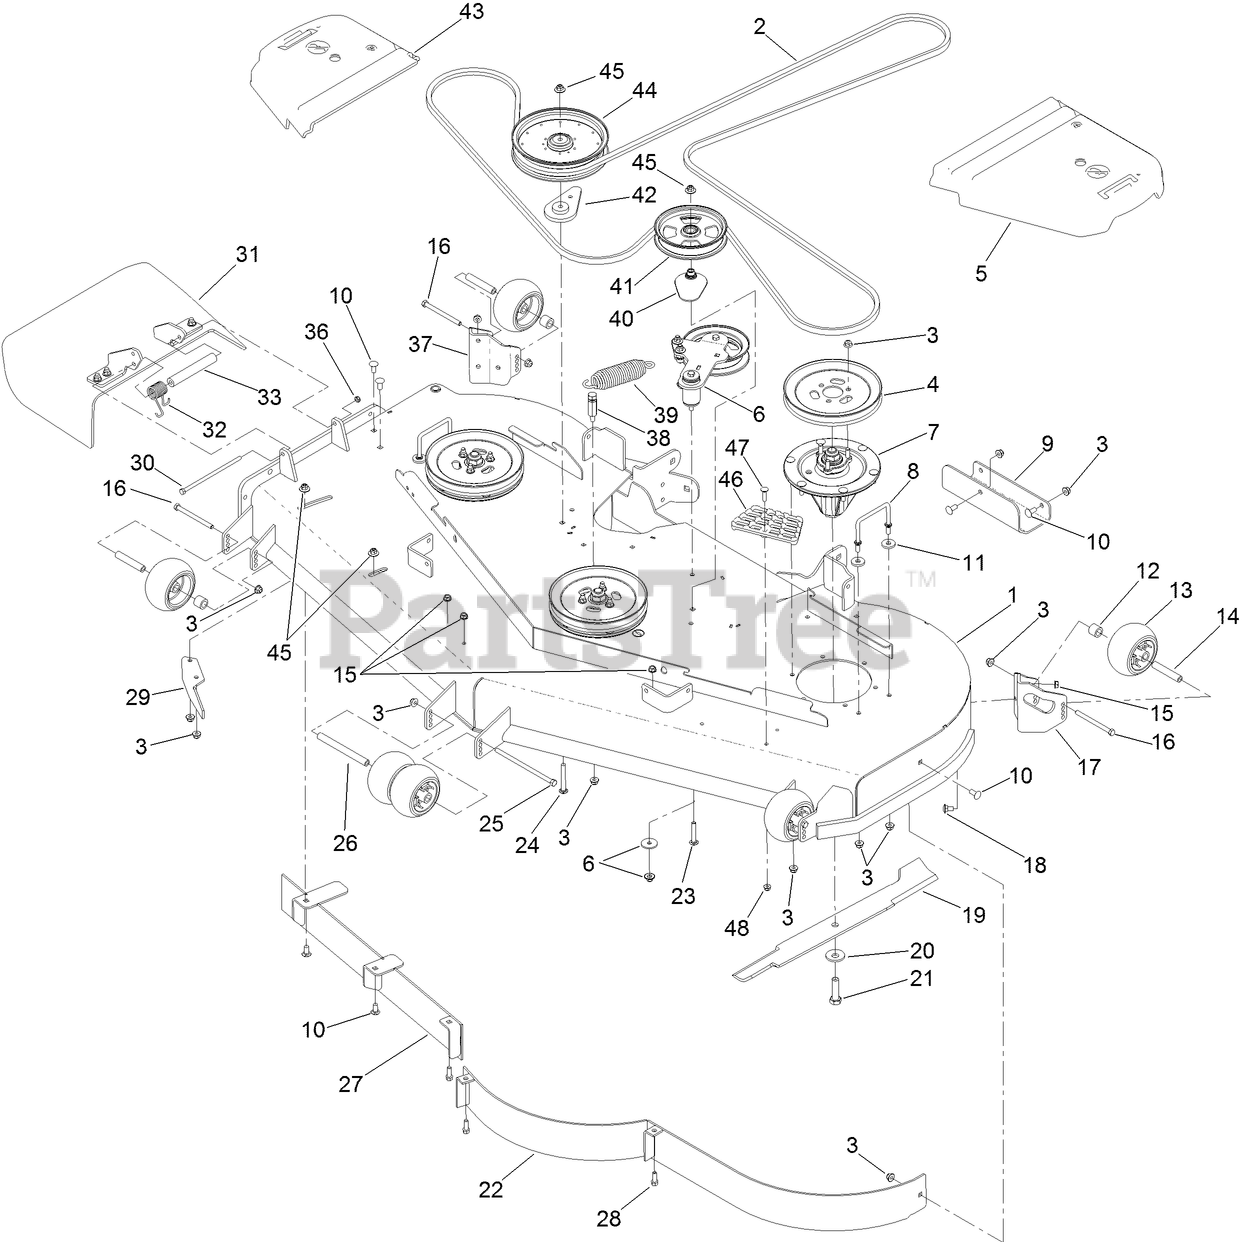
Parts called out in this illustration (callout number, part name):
1	DECK DECAL ASM
2	BELT-V
3	NUT-HF, NI
4	Pulley
5	COVER-BELT, LH
6	IDLER ARM ASM
7	SPINDLE ASM
8	WIREFORM-COVER
9	PLATE-SKID
10	SCREW-CARR
11	WASHER
12	TUBE-SPACER
13	ROLLER-SCALP, ANTI
14	TUBE-SPANNER
15	NUT-HHF, WHIZ
16	SCREW-HH
17	MOUNT-WHEEL, LH
18	SCREW-CARR
19	BLADE-HI FLOW, 24.5 INCH
20	Washer-Blade Bolt, Heavy
21	SCREW-BLADE
23	BOLT-CARR, SHORT NECK
24	SCREW-CARR
25	SCREW-HH
26	SPACER-WHEEL
28	SCREW-HWH
29	BAFFLE-DISCHARGE
30	SCREW-HH
31	RUBBER DEFLECTOR ASM
32	SPRING-TORSION
33	SPACER
36	NUT-LOCK, NI
37	MOUNT-WHEEL, RH
38	ANCHOR-SPRING, TALL
39	SPRING-EXTENSION
40	SPACER-PULLEY
41	PULLEY-IDLER, FLAT
42	SPACER-IDLER
43	COVER-BELT, RH
44	PULLEY-IDLER
45	NUT-FLANGE, NI
46	STEP-DECK
47	SCREW-CARR
48	NUT-HF, NI
